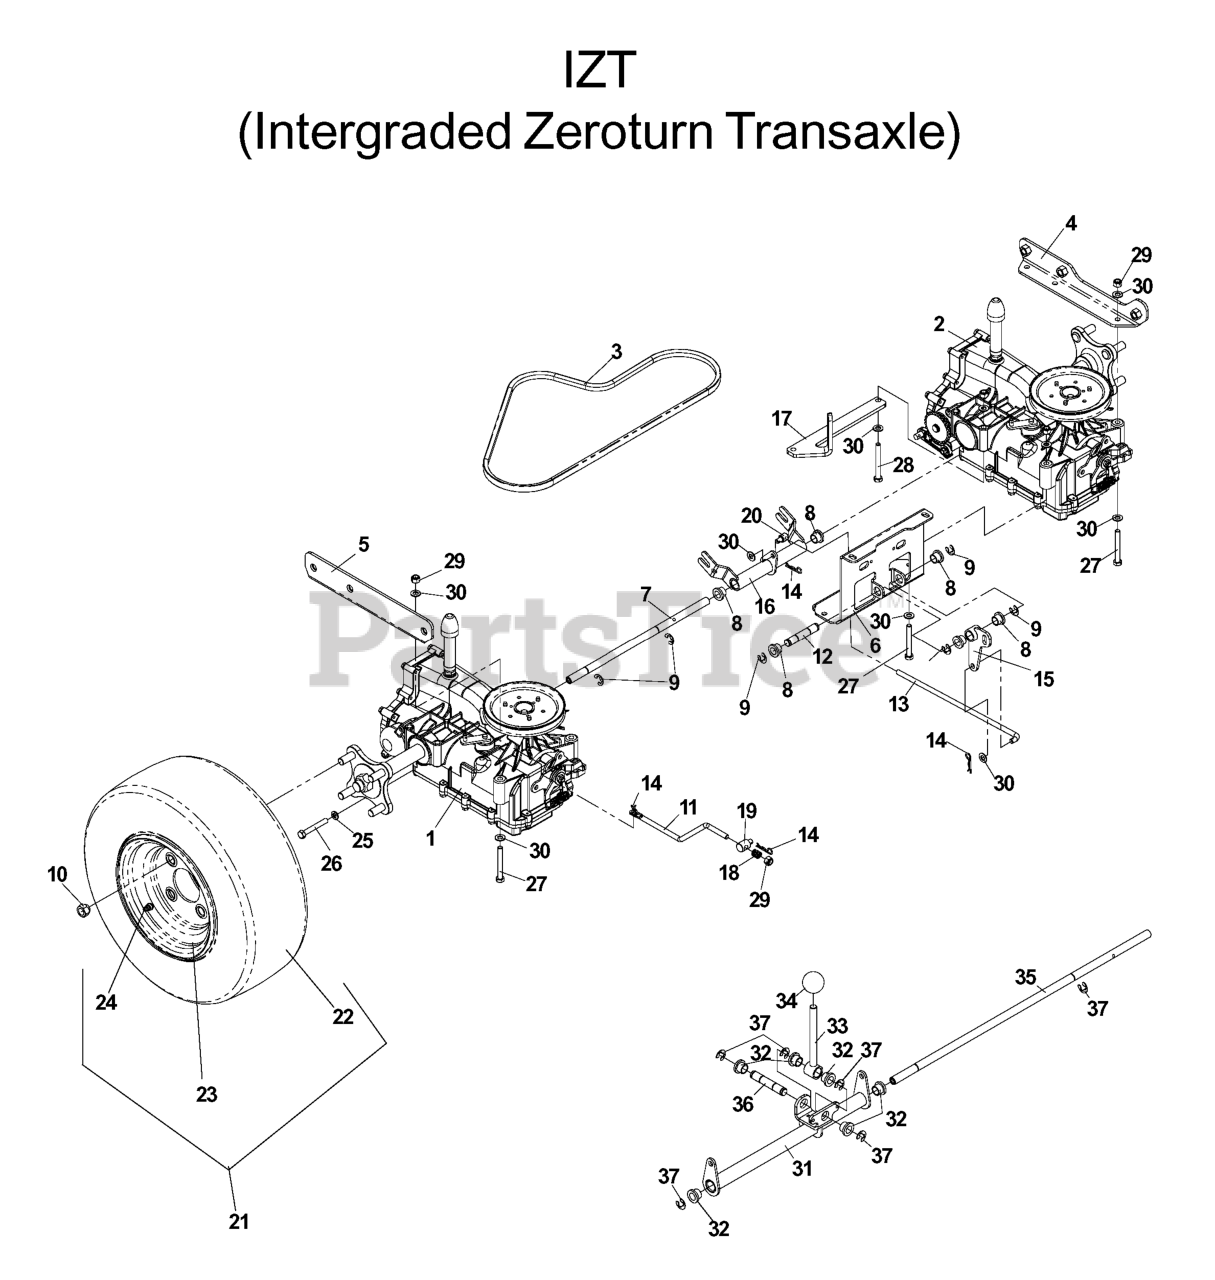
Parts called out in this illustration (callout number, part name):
1	HG_IZT LEFT (354-2400R)
2	HG_IZT RIGHT (354-2400L)
4	IZT SUPPORT RIGHT
5	IZT SUPPORT, LT
6	IZT SUPPORT, REAR
7	IZT CONNECTOR
8	BUSHING, FLANGED NYLON
9	E-RING 1/2 (2 2)
10	LUG NUT 1/2F
11	IZT BYPASS LINKAGE
13	BRAKE LINKAGE
14	HAIRPIN #2
15	BRAKE BELLCRANK, REAR
16	BRAKE BELLCRANK, FRONT
17	CLUTCH TIE DOWN
20	SWIVEL (SHORT)
21	TIRE/WHEEL.ASSEM.16X6.5-8.ZTR
22	TIRE, 16/650-8 TURF RIDER
24	VALVE STEM TR-412
25	WASHER.LOCK.HVY.HLCL.SPR.5/16
26	HEX SCREW-.313C X 2.25 GR8
27	BOLT 5/16C X 2 1/2
28	HCS 5/16C X 2-3/4
29	NUT 5/16 NYLOC
30	FLAT WASHER 5/16 SAE
31	ACTUATOR ARM
32	BUSHING, FLANGED NYLON
37	E-RING 1/2 (2 2)
539109000	HG_IZT LEFT
539109001	IZT RIGHT
